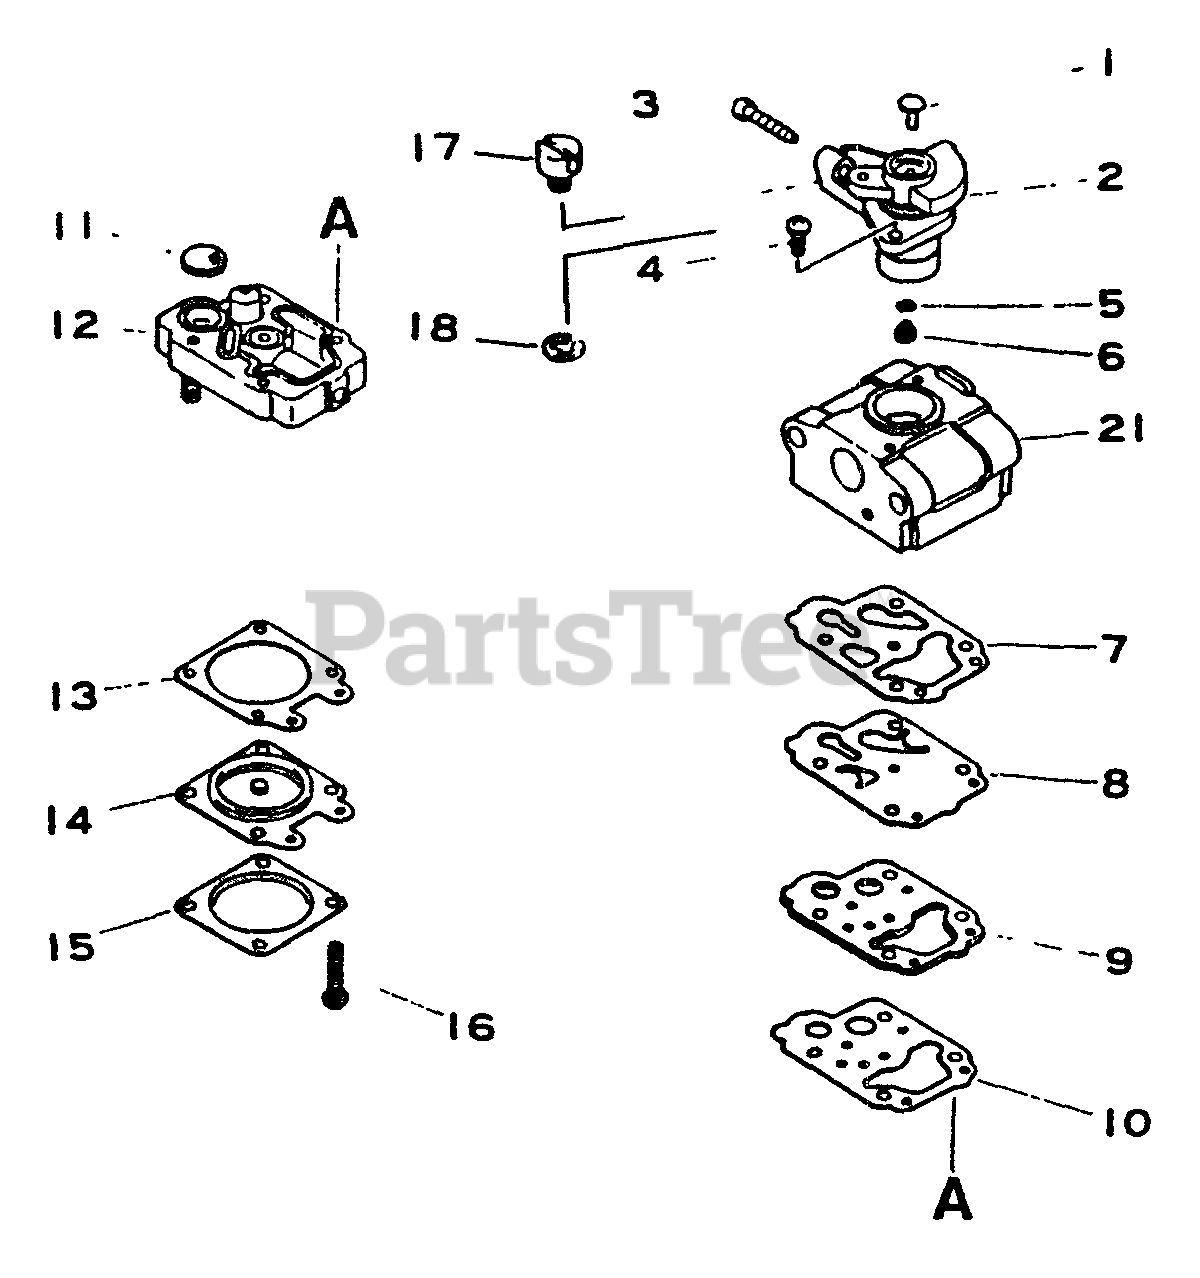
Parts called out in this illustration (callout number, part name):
1	PLUG, WELCH
2	THROTTLE VALVE ASSY
3	SCREW, IDLE ADJUST
5	O-RING
6	JET
7	GASKET, PURGE
8	DIAPHRAGM, PURGE
9	PLATE, PUMP
10	GASKET, PLATE
11	STRAINER
12	BASE, PURGE
13	GASKET, METERING
14	DIAPHRAGM, METERING
15	COVER, METERING
18	RING, RETAINING
21	Use Carb AsSy #12300045130
